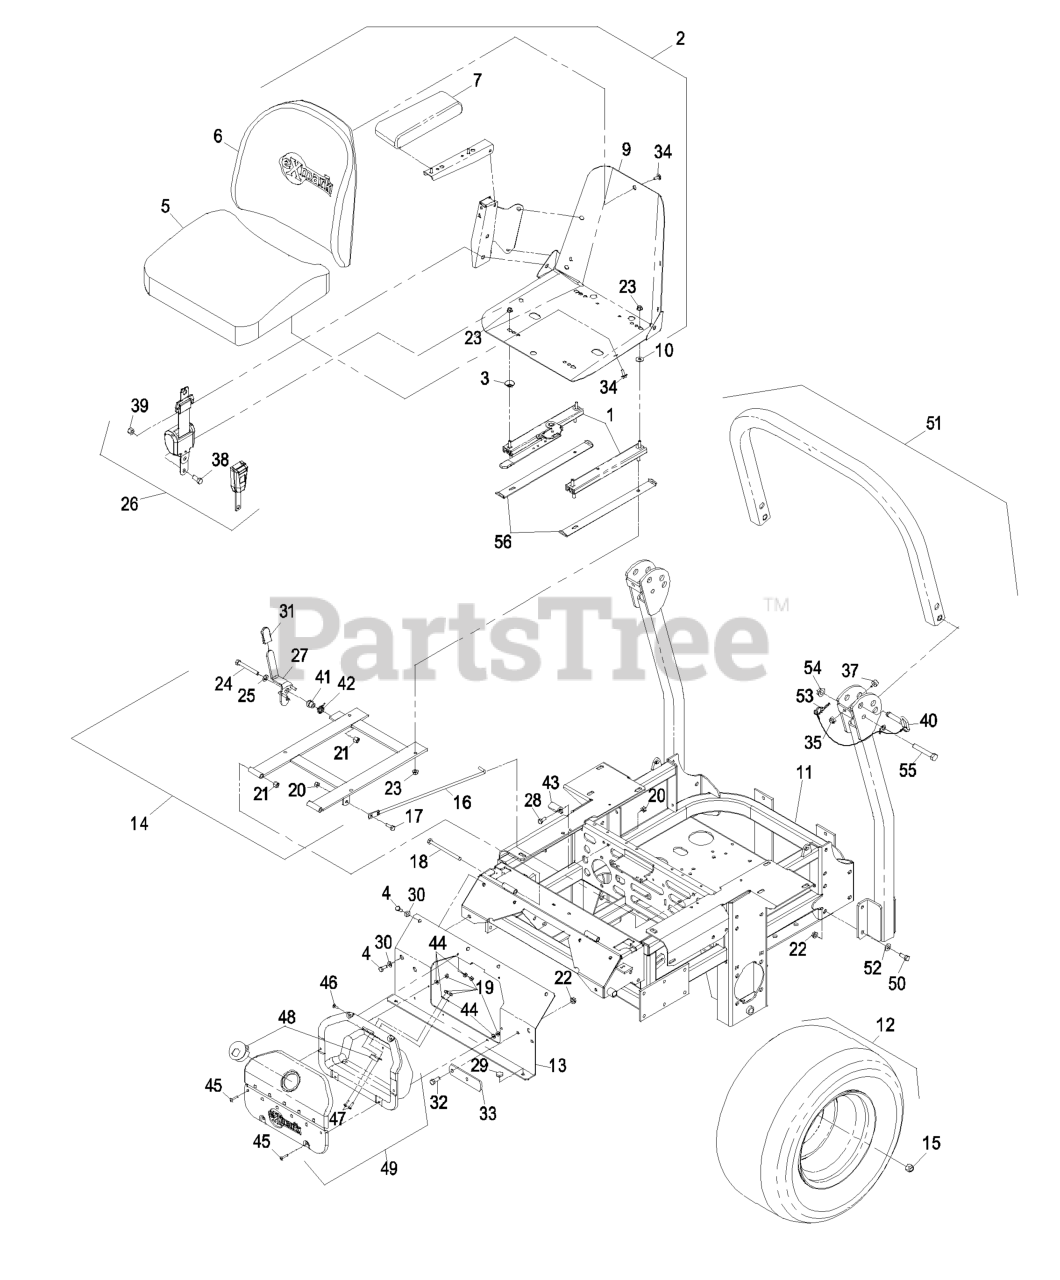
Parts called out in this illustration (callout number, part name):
1	TRACK-SEAT
2	KIT,SEAT W/ARMREST ADJ.
3	SPACER-TRACK
4	SCREW-HH
5	CUSHION,SEAT BOTTOM
6	CUSHION,SEAT BACK
7	CUSHION,ARMREST RH
9	FRAME-SEAT
10	WASHER-FLAT
11	ASM,MAINFRAME W/DECAL
12	WHEEL AND TIRE ASM
13	ASM, CONSOLE W/DECALS
14	ASM,SEAT FRAME
15	NUT-LUG
16	ROD-HOLDUP, SEAT
17	SCREW-HH
18	SCREW-HH
19	NUT-LOCK, NI
20	NUT-LOCK, NI
21	NUT-LOCK, NI
22	NUT-HHF, WHIZ
24	SCREW-HH
25	WASHER-FLAT
26	RETRACTABLE SEATBELT KIT
27	LATCH ASM
28	SCREW-HH
30	WASHER-PLAIN
31	GRIP-LEVER
32	SCREW-HH
33	STOP-BRAKE, PARK
34	BOLT-SEAT
35	NUT-LOCK, NI
36	SCREW-HH
37	BUMPER-RUBBER
38	SCREW-HH
39	NUT-LOCK
40	PIN-FOLD, ROPS
41	BUSHING-LATCH, SEAT
42	SPRING-TORSION
43	CATCH-LATCH, SEAT
44	WASHER-FLAT
46	SCREW-HEAD, TRUSS
47	SCREW-PPH
48	LATCH,CUBBY
49	ASM,CUBBY
50	SCREW-HH
51	KIT, ROPS LZ >510,000
52	WASHER-BELLEVILLE
53	HAIRPIN
55	SCREW-HH
